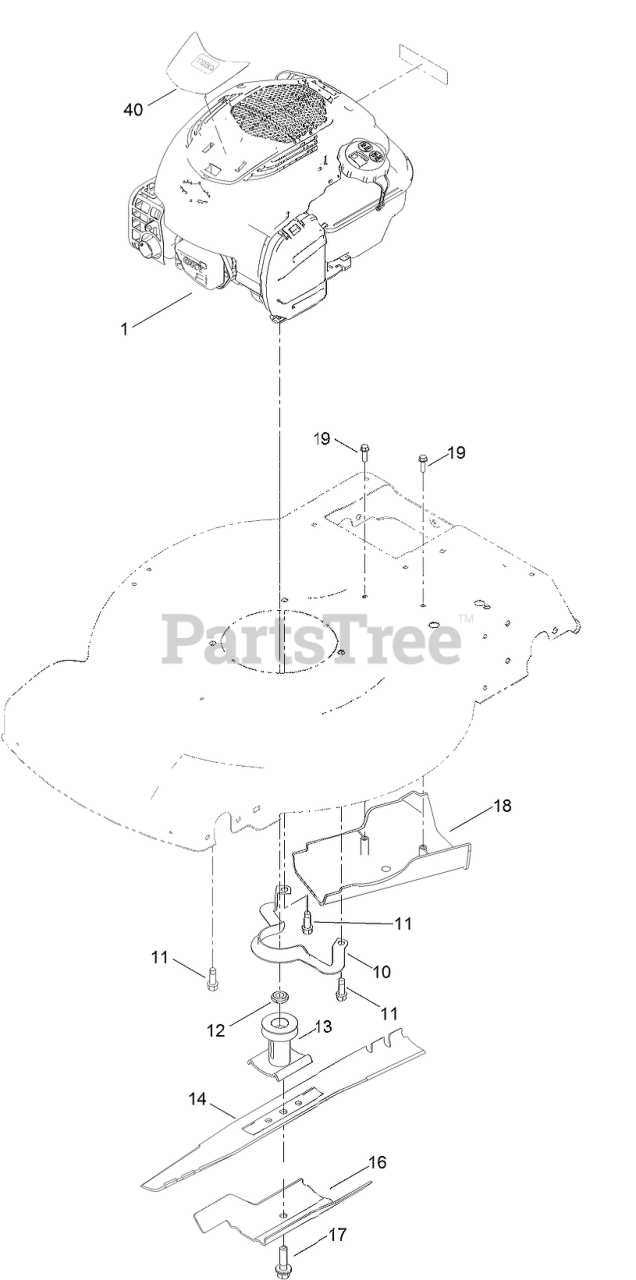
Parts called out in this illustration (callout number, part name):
10	GUIDE-BELT
11	SCREW-TAPTITE
12	SPACER-DRIVER
13	DRIVER-BLADE
16	ACCELERATOR-BLADE
17	BOLT-BLADE
18	COVER-BELT
19	SCREW-PLASTITE, HWH
40	DECAL-SHROUD
